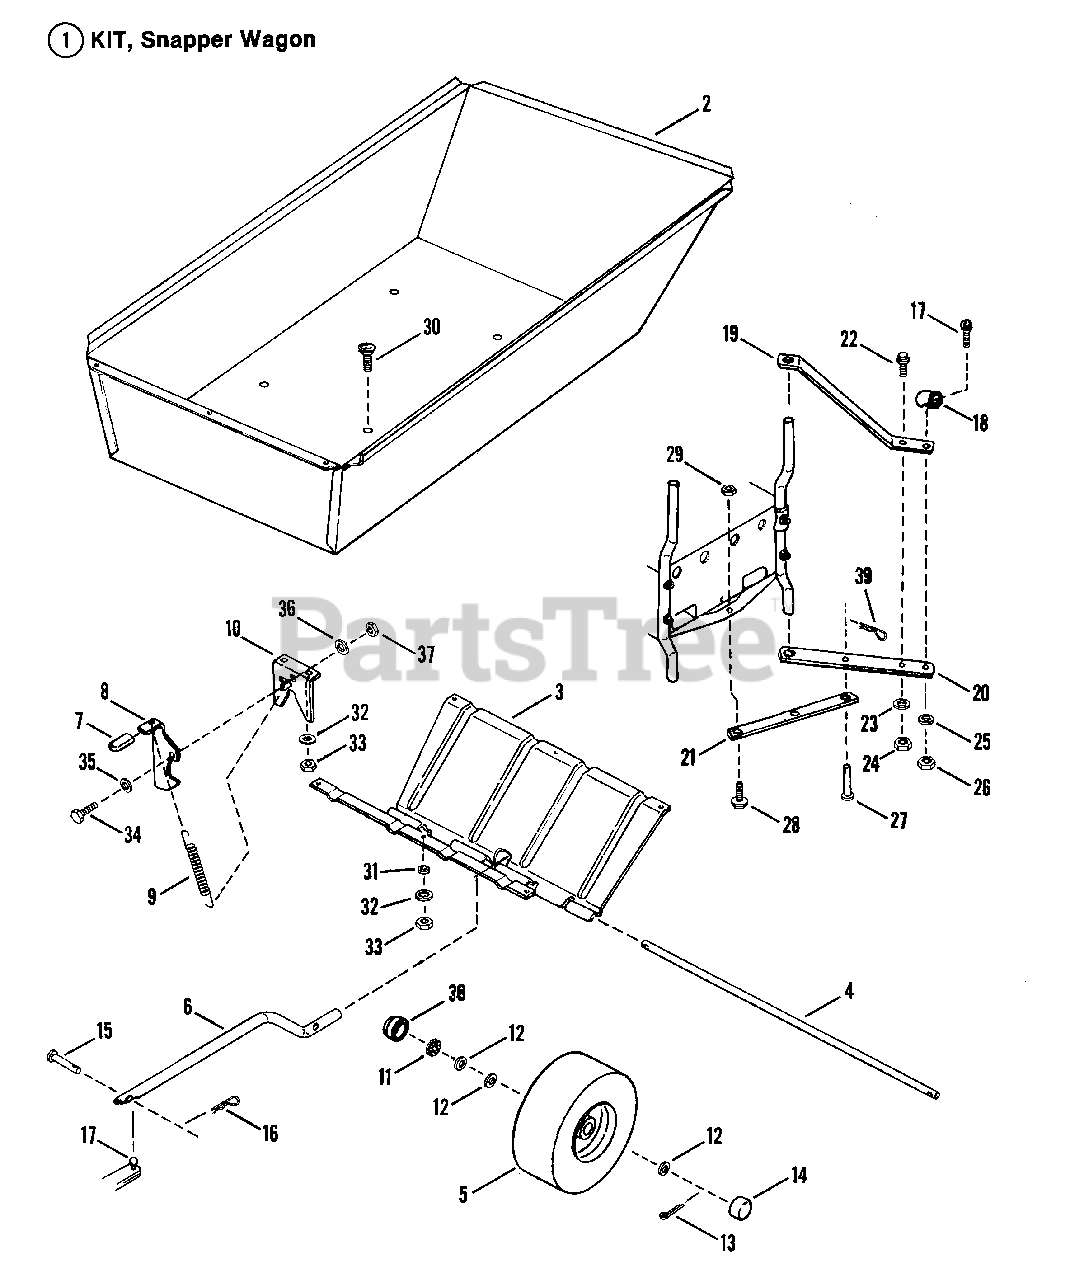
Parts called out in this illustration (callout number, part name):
1	KIT, Snapper Wagon
2	BODY, Wagon Cart
3	SUPPORT, Axle
4	AXLE
5	ASSEMBLY, Tire & Rim
6	TONGUE
7	GRIP, Latch
9	SPRING, Latch
10	YOKE
11	WASHER, Felt
12	WASHER
13	COTTER-PIN, 5/32x1"
14	COVER, Dust
15	PIN, 3/8 Clevis
16	PIN, Hair
17	BALL, Hitch
18	COLLAR, Hitch
19	BAR, Upper Draw
20	BRACE, Draw Bar
21	BAR, Lower Draw
22	CAPSCREW, 3/8-24x1" Hex Head
23	LOCKWASHER, 3/8 Split
24	NUT, 3/8-24 Hex
25	LOCKWASHER, 7/16 Split
26	NUT, 7/16-20 Hex
27	PIN, Hitch Clevis
28	CAPSCREW, 1/2-20x1" Hex Head
29	LOCKNUT, 1/2-20 Hex
30	CARRIAGE BOLT, 1/4-20x3/4"
31	RETAINER, 1/4 Bolt
32	LOCKWASHER, 1/4 Internal Tooth
33	NUT, 1/4-20 Hex
34	BOLT, 5/16-18 Shoulder
35	WASHER, Spring
36	LOCKWASHER, 5/16 Split
37	NUT, 5/16-18 Hex
38	DUST-CAP
39	PIN, Hair
